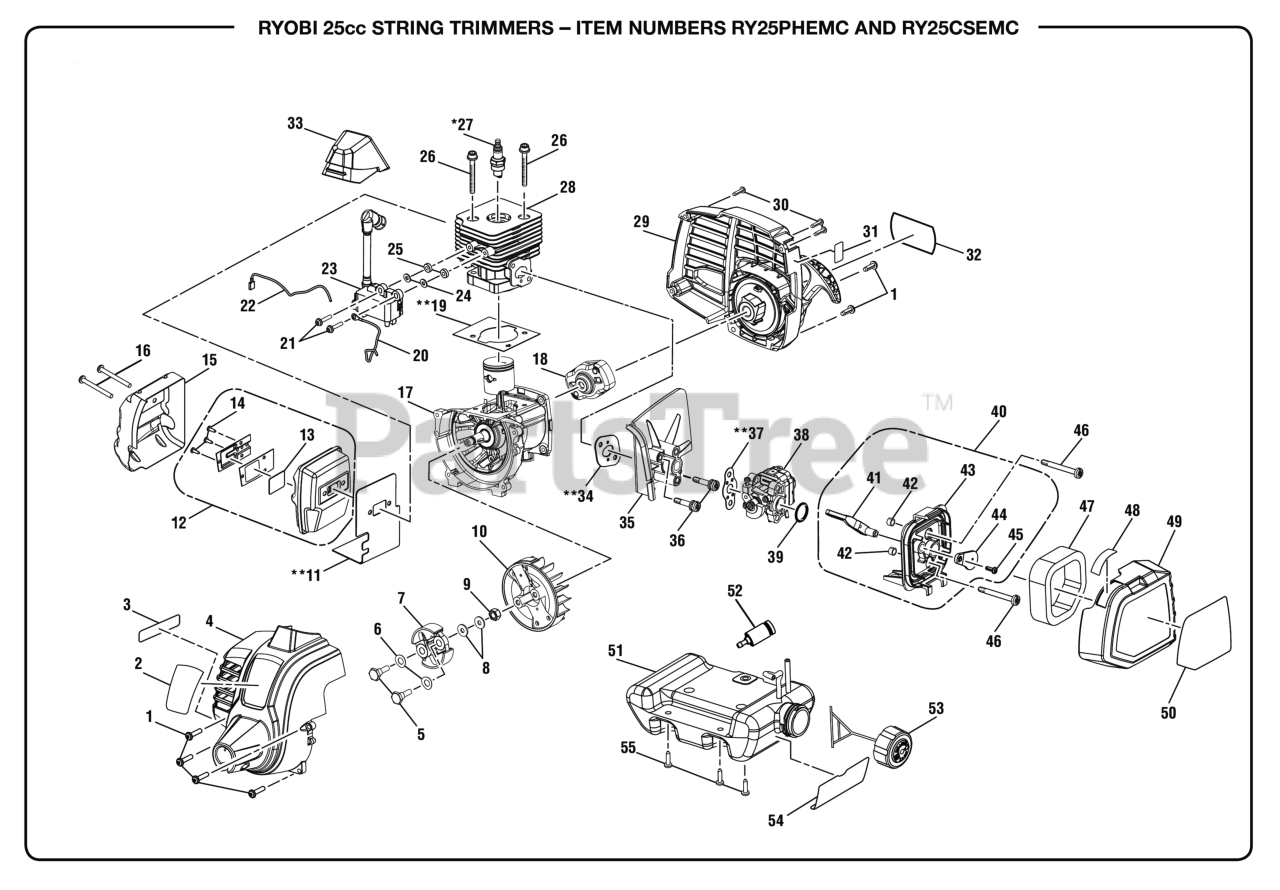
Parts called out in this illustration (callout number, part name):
1	Cap Screw w/Washer (M5 x 16 mm, T25 Torx Soc. Hd.)
2	Logo Label (Front)
3	Warning Label (Combustion)
4	Front Housing Assembly
5	Clutch Shoulder Bolt (M6 x 22.5 mm, Hex Hd.)
6	Washer (Curved)
7	Clutch Assembly
8	Washer (ID6 x OD15 x 1.2t)
9	Flange Nut (M8, Flywheel)
11	Muffler Gasket
12	Muffler Assembly
13	SCREEN
14	Screw (6-20 x 1/4 in., T20 Torx Pan Hd. S.T.)
15	HEAT SHIELD
16	Screw (M5 x 50 mm, Torx Slotted Recessed Pan Hd.)
17	Crankcase Assembly
18	Starter Cup
20	Lead Wire Assembly, Red
21	Screw (M4 x 22 mm, T20 Torx Slotted Recessed Pan Hd.)
22	Lead Wire Assembly, Black
23	Coil Boot Assembly
24	Flat Washer (OD10 x ID42 x 1t)
25	Phenolic Spacer (Ignition Module)
26	Screw (M5 x 22 mm, T25 Torx Soc. Hd.)
27	SPARK PLUG CHAMPION - RCJ-6Y
29	Rear Housing and Starter Assembly
30	Screw (M4 x 20 mm, T20 Torx Pan Hd. S.T.)
31	Primer Bulb Location Label
32	Shoulder Screw (M4 x 14 mm, T25 Torx Truss Hd.
33	Spark Plug Boot
34	Heat Dam Insulator
35	Screw (M5 x 30 mm, T25 Torx Pan Hd. S.T.)
36	Screw w/Washers (M5 x 30 mm, T25 Torx Pan Hd.)
37	Gasket
38	Carburetor Assembly
39	Carburetor O-Ring
40	Airbox Base Assembly
41	Compression Limiters
42	Washer (ID5.8 x OD11.5 x 1.7t)
43	Air Box Base
44	Screw (M4 x 12 mm, T20 Torx Pan Hd. S.T.)
45	Screw (M4 x 12 mm, Slotted Recessed Pan Hd.)
46	Screw (M5 x 44 mm,T25 Torx Hd. Carburetor)
47	Air Filter (Element)
48	Choke Position Label
49	Airbox Cover (Inc. Key Nos. 48 & 50)
50	Starting Instructions Label
51	Fuel Tank and Cap Assembly
52	Fuel Filter
53	Fuel Cap Assembly
54	Fuel Mixture Label
55	Shoulder Screw w/Washer (M4 x 14 mm, T25 Torx Truss Hd.)
